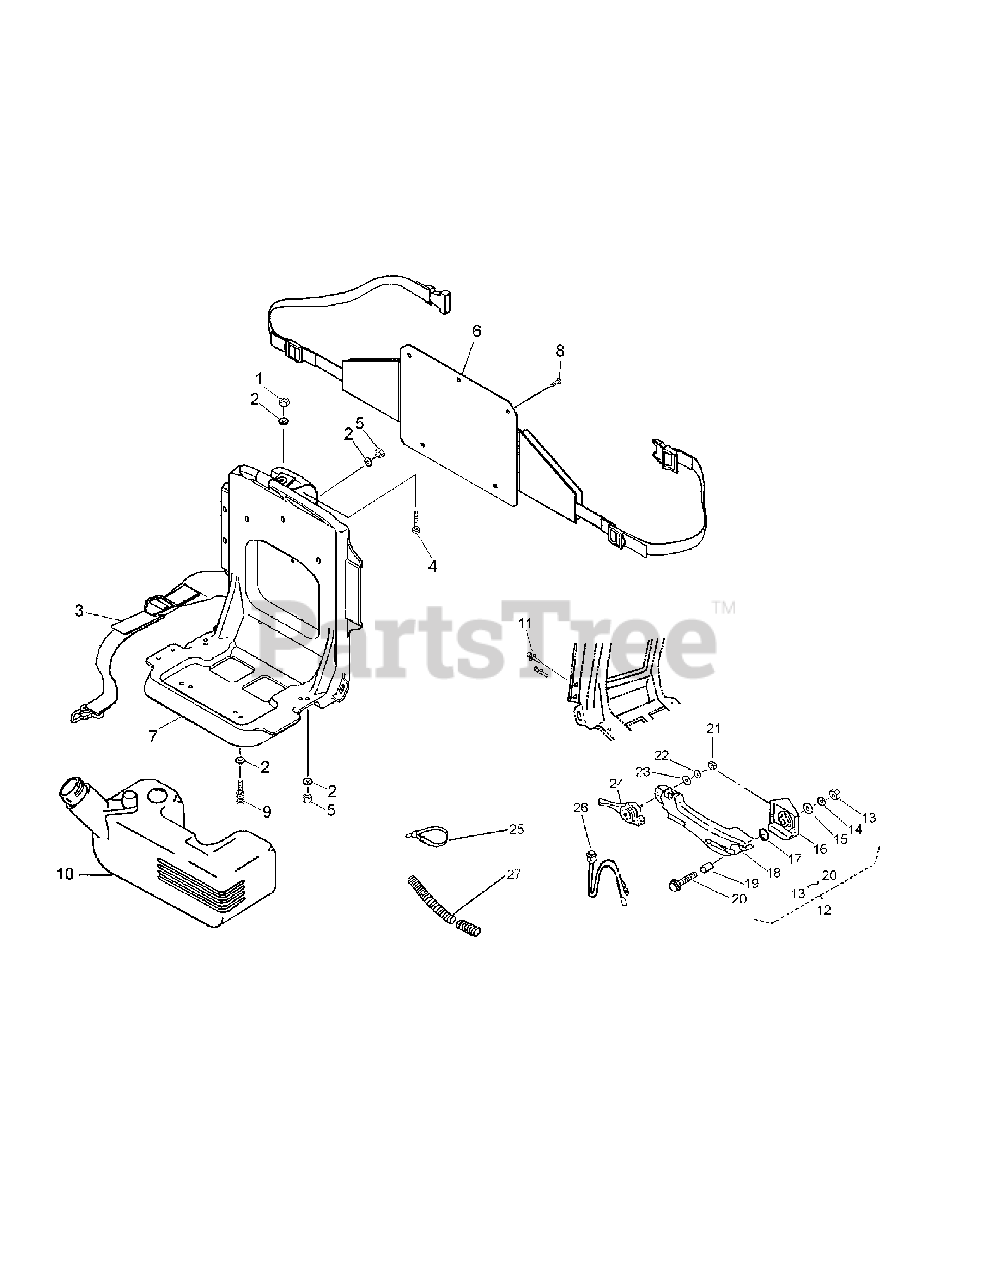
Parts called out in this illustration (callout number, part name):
1	FLANGE NYLON NUT M6
3	SHOULDER BAND
4	TRUSS SCREW M6x16
5	U-HEXAGON NUT M6
6	KNAPSACK PAD
7	KNAPSACK FRAME
9	SCREW(W/SW) M6x15
11	SCREW(W/SW,PW) M5x12
12	LEVER C.P. (INC. REF 13-20)
13	HEXAGON NUT M8
14	SPRING LOCK WASHER M8
15	PLAIN WASHER M8
20	FLANGE BOLT M8x25
21	HEXAGON NUT M5
22	SPRING LOCK WASHER M5
23	PLAIN WASHER M5
24	THROTTLE LEVER
